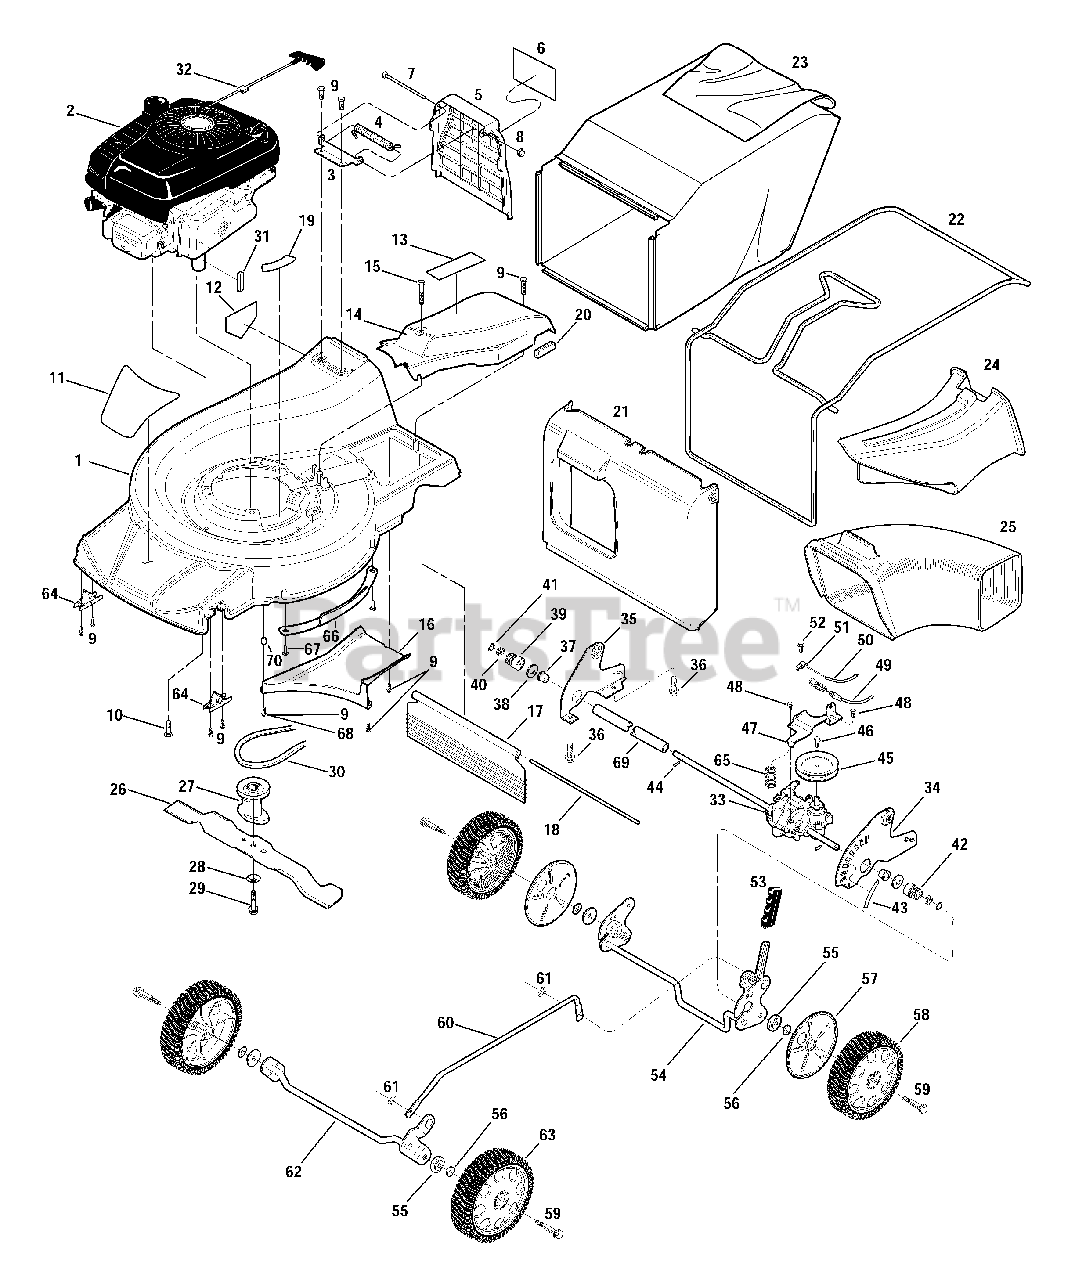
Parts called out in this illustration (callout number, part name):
1	Mower Deck
2	Engine
3	Support Bracket
4	Torsion Spring
5	Discharge Outlet Cover
6	Decal - Warning
8	Flange Push Nut, 5/16 dia
9	Hex Hd. Flange Screw, 1/4-20 x 3/4, Self-Thrd.
10	Hex Hd. Screw, 3/8-16 x 1-1/4, Self-Thrd.
11	Decal - Logo
12	Decal - Danger, Hands/Feet Away
13	Decal - Warning, Belt Cover
14	Belt Cover
15	Hex Hd. Flange Screw, 1/4-20 x 2-1/4, Self-Thrd.
16	Discharge Outlet Baffle
17	Safety Flap
19	Decal - Danger, BBC Opening
20	Rubber Extrusion
21	Grass Catcher Door
22	Grass Catcher Frame
23	Grass Catcher Bag
24	Mulching Plug
25	Side-Discharge Deflector
26	Mower Blade
27	Engine Pulley/Blade Coupler Assy.
28	Belleville Washer, 1/2"
29	Shoulder Screw, 3/8-24 x 1.65
31	Square Key, .188 x 1-1/4
32	Rope Stop
33	Transaxle
34	Handle Support Bracket, Left-Hand
35	Handle Support Bracket, Right-Hand
36	Hex Hd. Flange Screw, 3/8-16 x 3/4, Self-Thrd.
37	Rear Axle Bearing
38	Washer/Seal, Nylon
39	Pinion Gear, Right-Hand
40	Shim, .016"
41	Snap Ring
42	Pinion Gear, Left-Hand
43	Decal - Blade Cutting Height
44	Round Pin
45	Transaxle Pulley
46	Hex Hd. Screw, 1/4-20 x 5/8, GR. 5
47	Cable Mounting Bracket
48	Hex Flange Hd. Screw, 1/4-20 x 1/2, Self-Thrd.
49	Drive Control Cable
50	Speed Control Cable/Lever
51	Cable Clamp
52	Hex Washer Hd. Flange Screw, #10-24 x 1/2
53	Lever Grip
54	Rear Axle Assembly
56	Flat Washer, .406" ID
57	Wheel Shield
58	Rear Wheel/Tire Assembly
59	Shoulder Screw, 3/8-16 x 2.42
60	Deck Height Adjust Linkage
61	E-Clip
62	Front Axle Assembly
63	Front Wheel/Tire Assembly
64	Front Axle Bearing
65	Compression Spring
66	Skid Plate
67	Pan Hd. Screw, 1/4-20 x 1/2
68	Pan Hd. Screw, 1/4-20 x 1
69	Spacer Tube, Plastic
70	Spacer, Steel
